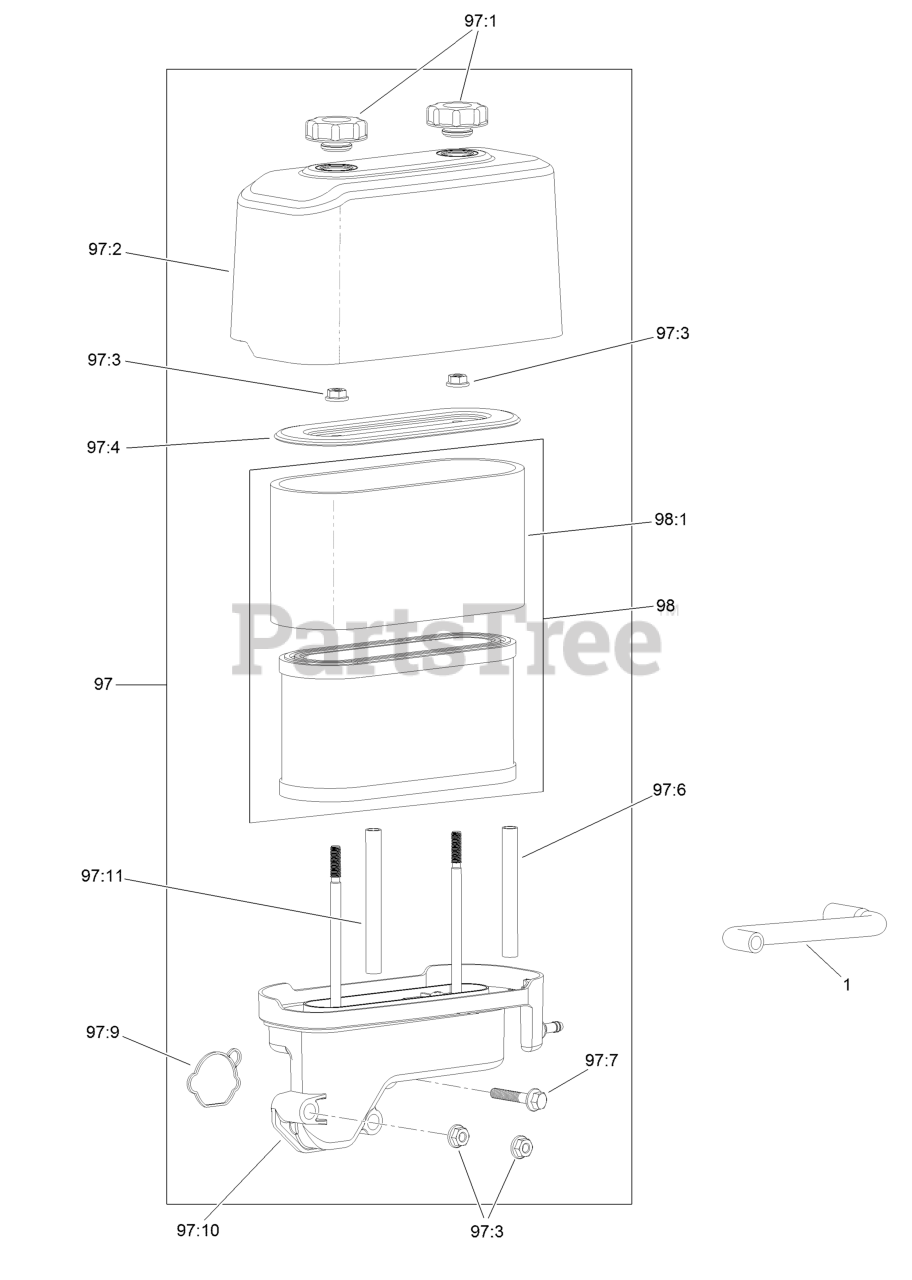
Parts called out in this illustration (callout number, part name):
1	TUBE-BREATHER
97:1	NUT-SPEED
97:2	COVER-FILTER, AIR
97:3	NUT-FLANGE
97:6	SPACER-FILTER, AIR
97:7	SCREW-HHF
97:9	GASKET-CARBURETOR
97:11	SPACER-FILTER, AIR
98:1	PREFILTER
